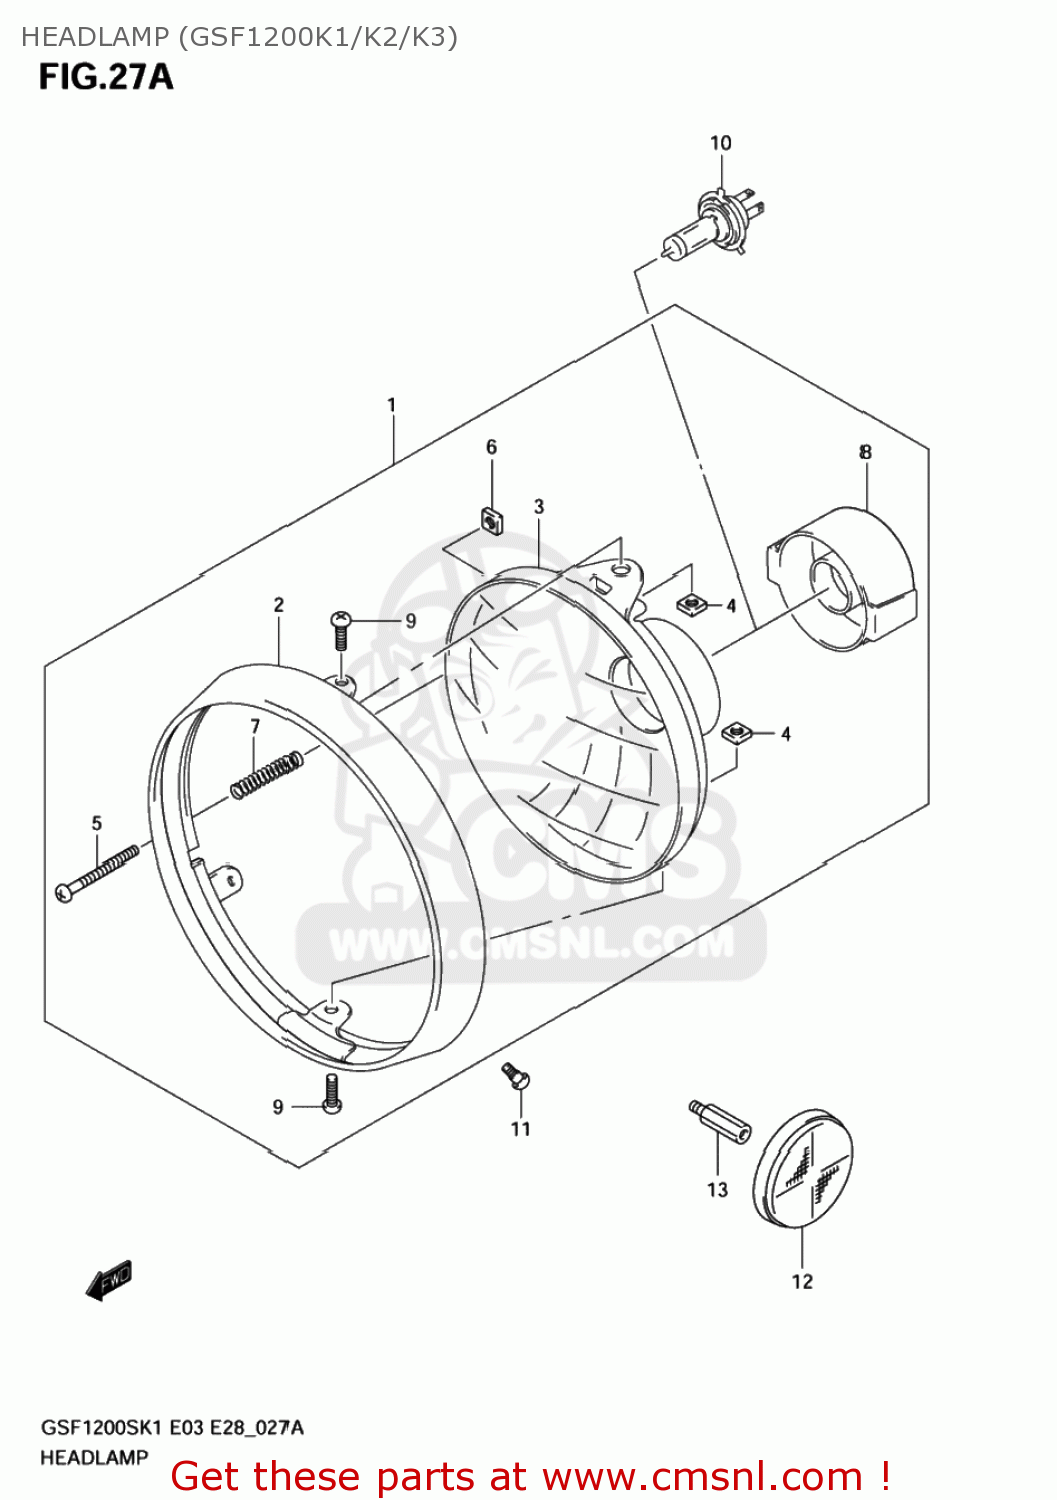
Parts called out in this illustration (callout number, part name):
1	HEADLAMP ASSY
2	RIM
3	LAMP UNIT
4	NUT
5	SCREW,ADJUSTING
6	NUT,HEADLAMP ADJUST
7	SPRING
8	COVER,SOCKET
9	SCREW(5X16)
10	BULB(12V60/55W,H4)
11	SCREW(5X15.3)
12	REFLECTOR,REFLEX FR
13	BOLT(5X10)
